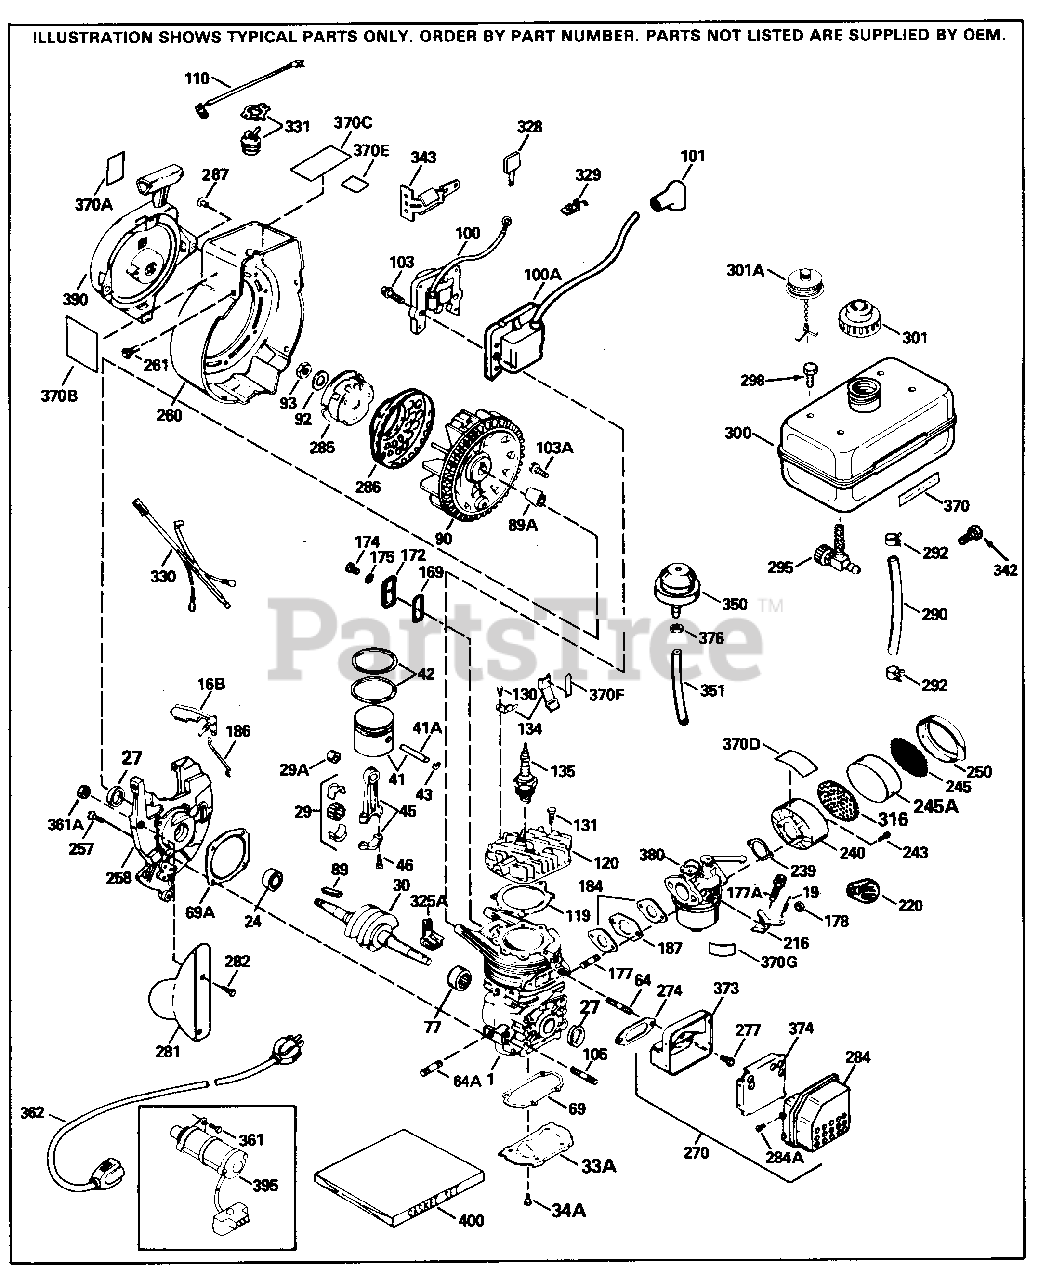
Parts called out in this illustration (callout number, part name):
1	"Cylinder Order s/b if replacement is req.
16B	Air Vane
19	Extension Spring
24	Ball Bearing
27	Oil Seal
29	Needle Bearing & Liner Set 30 needle s
29A	Cartridge Bearing
30	Crankshaft
33A	Cover Plate
34A	Screw, Torx T-25, 10-24 x 1/2"
41	Piston & Pin Assy. (Incl. 43)
41A	Piston Pin
42	Ring Set
43	Piston Pin Retaining Ring
45	Connecting Rod Assy. Incl. 29, 29A & 46
46	Connecting Rod Bolt
69	* Cover Plate Gasket
69A	* Cylinder Cover Gasket
77	Cartridge Bearing
89A	Adapter Sleeve
90	Flywheel
92	Belleville Washer
93	Flywheel Nut
100A	Solid State Ignition (Incl. 101)
101	Spark Plug Cover
103	Screw, Torx T-15, 10-24 x 1"
119	* Cylinder Head Gasket
120	Cylinder Head
131	Screw, Torx T-30, 1/4-20 x 3/4"
135	Resistor Spark Plug (RCJ-8Y)
169	* Cover Gasket
172	Compression Release Cover
174	Screw, Torx T-25, 10-24 x 1/2"
175	Washer, No. 10
177	Carburetor Stud, 1/4-28 x 1-1/4"
178	Nut & Lock Washer 1/4-28
184	* Carburetor Gasket
186	Governor Link
216	R.P.M. Adjusting Lever
257	Screw, 1/4-20 x 5/8"
258	Blower Housing Base (Incl. 75)
260	BLOWER HSG
261	Screw, 1/4-20 x 1/2"
270	Muffler Assy. (Incl. 277,284,284A,373 ,3 74) NOTE: Muffler Assembly 39 0263B has been replaced by the new on epiece muffler, Ref. 275.
274	* Exhaust Gasket
277	Screw, 1/4-20 x 5/8"
284	Muffler Cover NOTE: This muffler cov er has been replaced by the new one p iecemuffler, Ref. #'s 275, 275A or 27 5B.
284A	Screw, 8-18 x 3/8"
285	Starter Cup
287	Pop Rivet (3/16" dia.) Purchase local ly
300	Fuel Tank (Incl. 292)
301	Fuel Cap
325A	Spark Plug Wire Clip
330	Wire Harness
350	Primer Bulb
351	Primer Line
373	Muffler Base
374	Muffler Baffle
380	Carburetor (Incl. 184) (Refer to Divi sion 5, Section A, page A1-38 or Fich e 27A, Grid F-3 for breakdown)
390	Rewind Starter Refer to Division 5, S ection C, page 25 or Fiche 27A, Grid G-9 for breakdown
400	* Gasket Set (Incl. items marked *)
